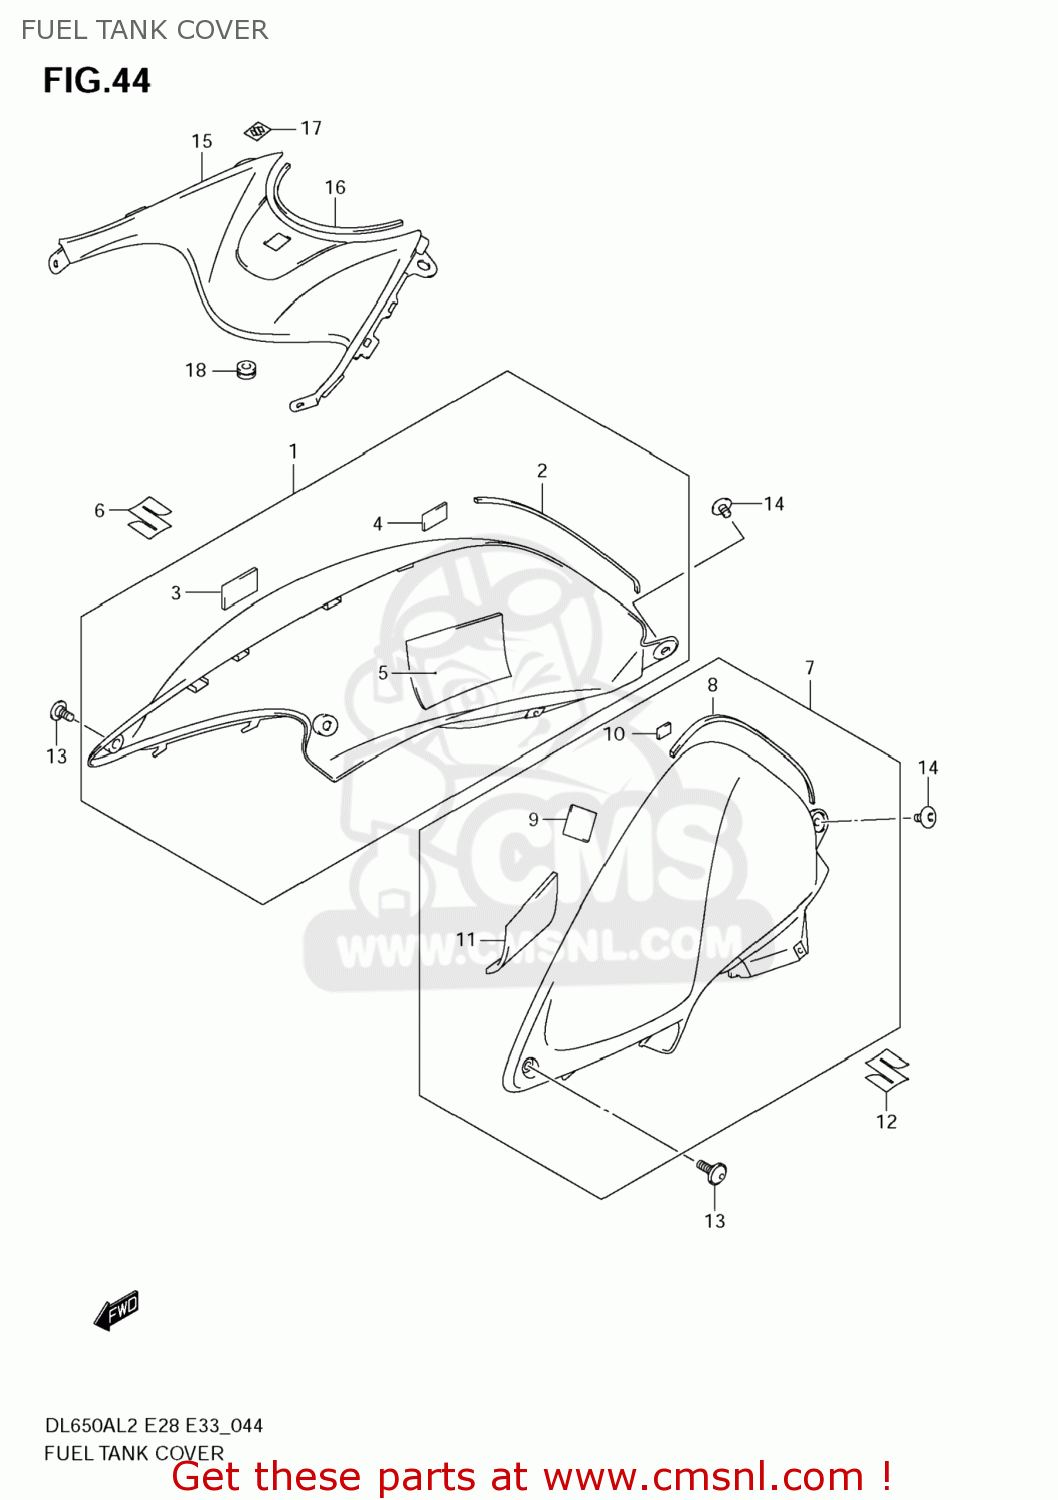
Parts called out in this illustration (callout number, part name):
1	COVER,FUEL TANK SIDE,R(WHITE)
2	CUSHION,FUEL TANK COVER
3	FASTENER
4	FASTENER
5	CUSHION,FUEL TANK
6	EMBLEM,S
7	COVER,FUEL TANK SIDE,L(WHITE)
8	CUSHION,FUEL TANK COVER
9	FASTENER
10	FASTENER
11	CUSHION,FUEL TANK
12	EMBLEM,S
13	SCREW(5X13)
14	BOLT(6X8)
15	COVER,FUEL TANK FR
16	CUSHION,FUEL TANK FR COVER
17	EMBLEM,S
18	CUSHION
